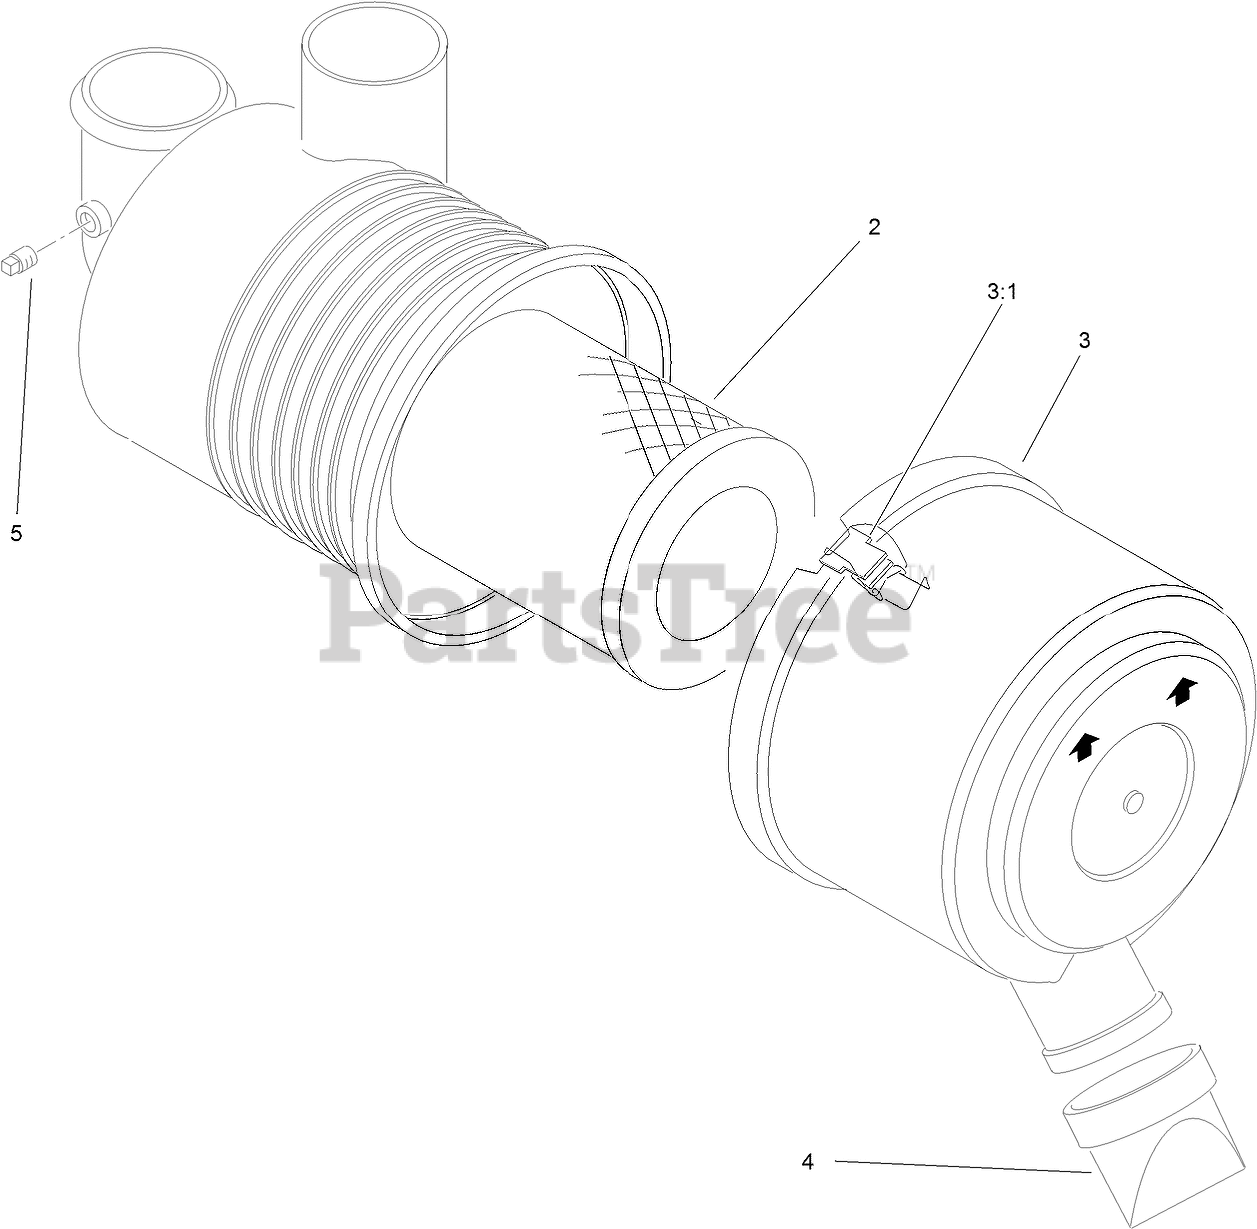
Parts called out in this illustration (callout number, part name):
2	FILTER-AIR
3	COVER ASM
3:1	LATCH-CLEANER, AIR
4	VALVE-VACUATOR
5	PLUG-PIPE
